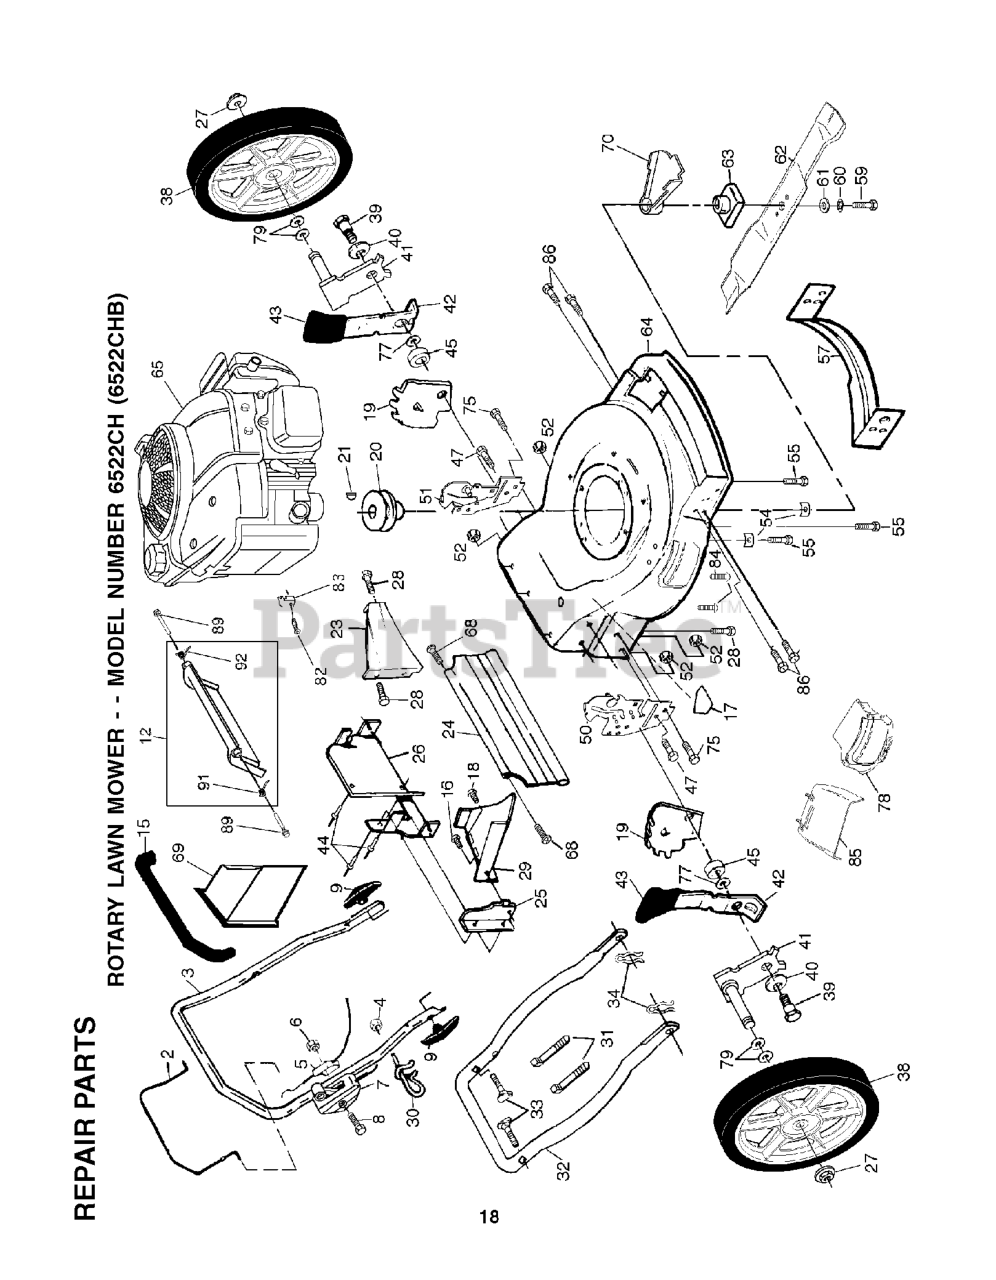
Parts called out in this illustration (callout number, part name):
2	CONTROL BAR
3	HANDLE, UPPER DLX COMF. (GRIP)
4	NUT
5	CABLE.MZR.51.RT.SP./PU.
6	NUT
7	THROTTLE CONTROL
8	SCREW 1/4-20 X 2.12
9	HANDLE KNOB
12	REAR DOOR KIT
15	GRIP.HANDLE.FOAM
16	SCREW.HXTAP.10-24
17	DECAL HYT
18	SCREW.HXTAP.10-24
19	WHEEL ADJ BRKT
20	ENGINE.PULLEY.FWG
21	HI PRO KEY PM WSL
23	REAR BAFFLE
24	REAR SKIRT
25	SIDE BAFFLE
26	BACK PLATE
27	HEX FLANGE LOCKNT
29	DISCHARGE BAFFLE
30	ROPE, GUIDE
31	TIE GUIDE
32	LOWER HANDLE
33	HANDLE BOLT
34	HAIRPIN COTTER
38	WHEEL.14X2.PR.SP.RAD.GY
39	BOLT
40	WASHER
41	AXLE ARM ASM
42	SELECTOR SPRING
43	SELECTOR KNOB
44	RIVET BLIND
45	RP SPACER HT ADJ
47	SELF-TAPPING SCREW 5/16-18X3/4
50	HANDLE BRKT (R)
51	HANDLE BRKT (L)
52	LOCKNUT PM
54	WASHER.ENGINE.BZP
55	BOLT 3/8-16X1-1/8
57	KIT.BAFFLE.FRT.22RD.FO.PU/FWGD
59	SCREW, HEX HD 3/8-24 X 1-3/8
60	LOCKWASHER
61	WASHER,HARDEN
63	BLADE ADAPTOR
64	MWR HOUSING KIT
68	HINGE SCREW
69	PLUG.MULCH.22RD
70	DEBRIS SHIELD
77	WASHER.FLAT.1/2
78	MULCH DOOR
79	WAVE WASHER
82	SCREW.HEX.HEAD.WASHER.10-16
83	WASHER
84	NUT
85	CLIP-ON DISCHARGE
86	SCREW 1/4X20
89	DOOR BOLT
91	DOOR SPRING RH
92	DOOR SPRING LH
